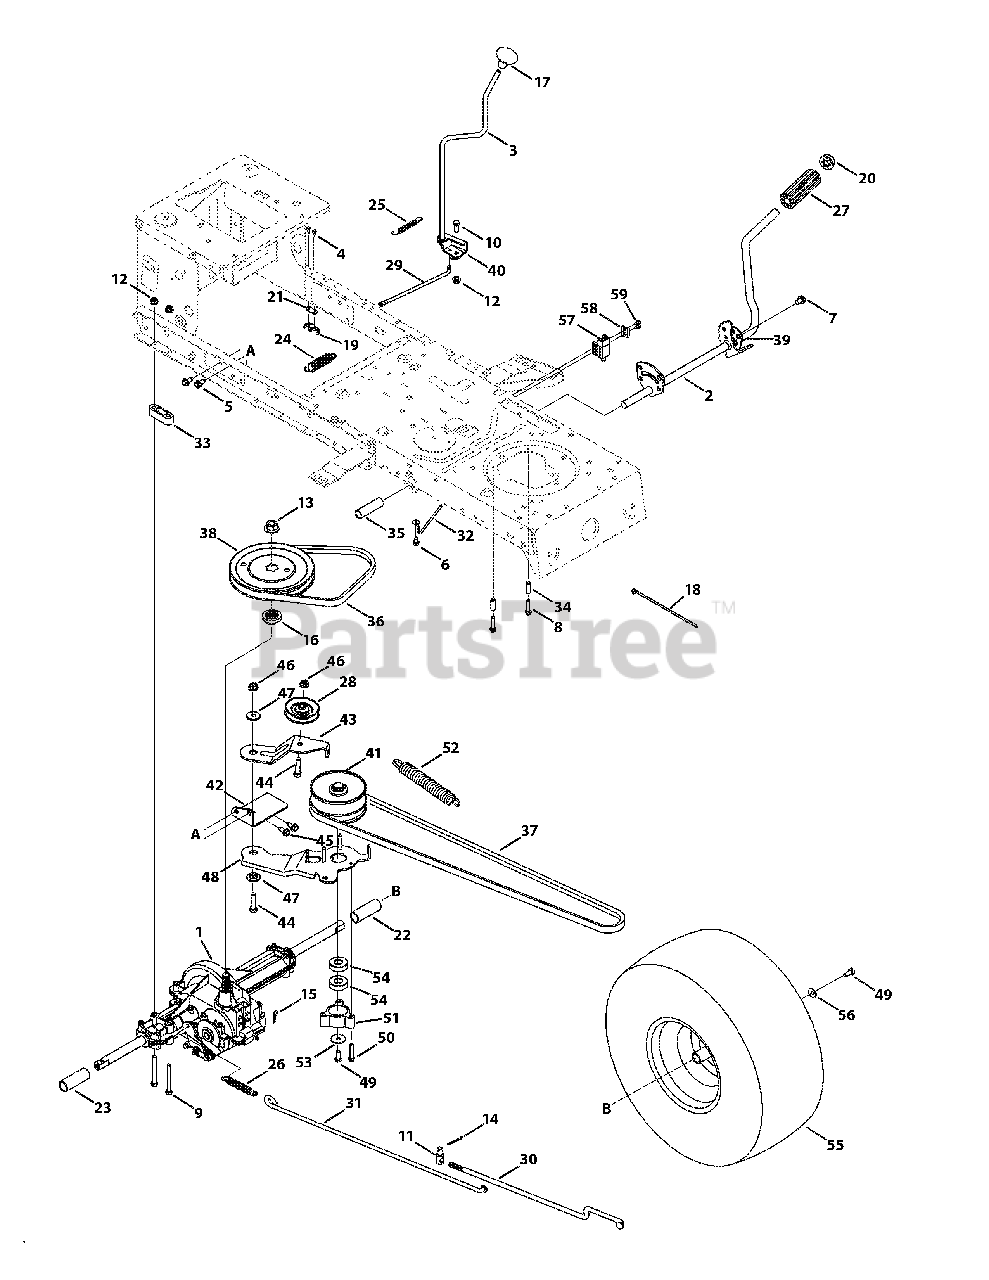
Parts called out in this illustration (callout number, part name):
1	Transmission Drive Assembly, Raised
2	Pedal Assembly
3	Shaft Lever Assembly
4	Screw, 8-18:0.500
5	Screw, 5/16-18 x .750
6	Screw, 1/4-20 x 0.500
7	Screw, 5/16-18 x 0.625
8	Screw, 1/4-20 x 1.250
9	Hex Screw, 5/16-18 x .625
9	Hex Screw, 5/16-18 x 2.75
10	Hex Screw, 5/16-18 x .75
11	Ferrule, 3/8-24 X .375 DIA.
12	Flangelock Nut, 5/16-18
13	Flange Nut, 9/16-18
14	Cotter Pin, 1/8 x 1.0
15	Cotter Pin INT- .125 DIA
16	Pulley Hub, 5/8 SPLINE
17	Shift Knob
18	Cable Tie
19	Short Spring Switch
20	Push Cap, 5/8
21	Plate Insulator Nut
22	Sleeve, .758 x .821 x 3.3125
23	Sleeve, .758 x .821 x 2.4375
24	Spring Extension, .80 OD x 3.28 LG
25	Spring Extension, .38 OD x 3.25 LG
26	Spring Extension, .59 OD x 4.00 LG
27	Foot Pad, 4.0 LONG
28	Idler Pulley
29	Shift Rod, 46"
29	Shift Rod. 38/42"
31	Brake Rod
32	Belt Keeper Rod
33	Spacer, T-Axle, 46" Only
34	Spacer, .260 x .375 x 1.030 LG
35	Spacer, .640 ID x .76 OD x 2.63
36	V Belt, 5L:35.25:POLY
37	V Belt, 5L:68.90:POLY
38	V Pulley:7.25 DIA SPUN
39	Pedal Support Bracket
40	Shaft Adjust Bracket
41	Variable Speed Pulley Assembly
42	Transmission Bracket Assembly
43	Idler Bracket Assembly
44	Hex Screw, 3/8-16 x 1.75
45	Screw, 5/16-18 x 0.750
46	Flangelock Nut, 3/8-16
47	Shoulder Spacer, .625 ID x .169
48	Bracket Assembly
49	Hex Screw, 5/16-24 x .750
50	Screw, 1/4-20 x 1.500
51	Bearing Cup
52	Extension Spring, 1.15 OD x 7.90 LG
53	Flat Washer, .330 x 1.25 x .06:HT
54	Ball Bearing, 17 x 40 x 12
55	Wheel, 20 x 8 x 8, 46" - Gray
55	Wheel, 20 x 8 x 8, 46" - Yellow
55	Wheel, 20 x 8 x 8, 42" - Gray
55	Wheel, 20 x 8 x 8, 42" - Yellow
56	Bell Washer, .340 x .872 x .060
57	Switch Interlock
58	Plate Switch
59	Shoulder Screw, #10-32 x .500
